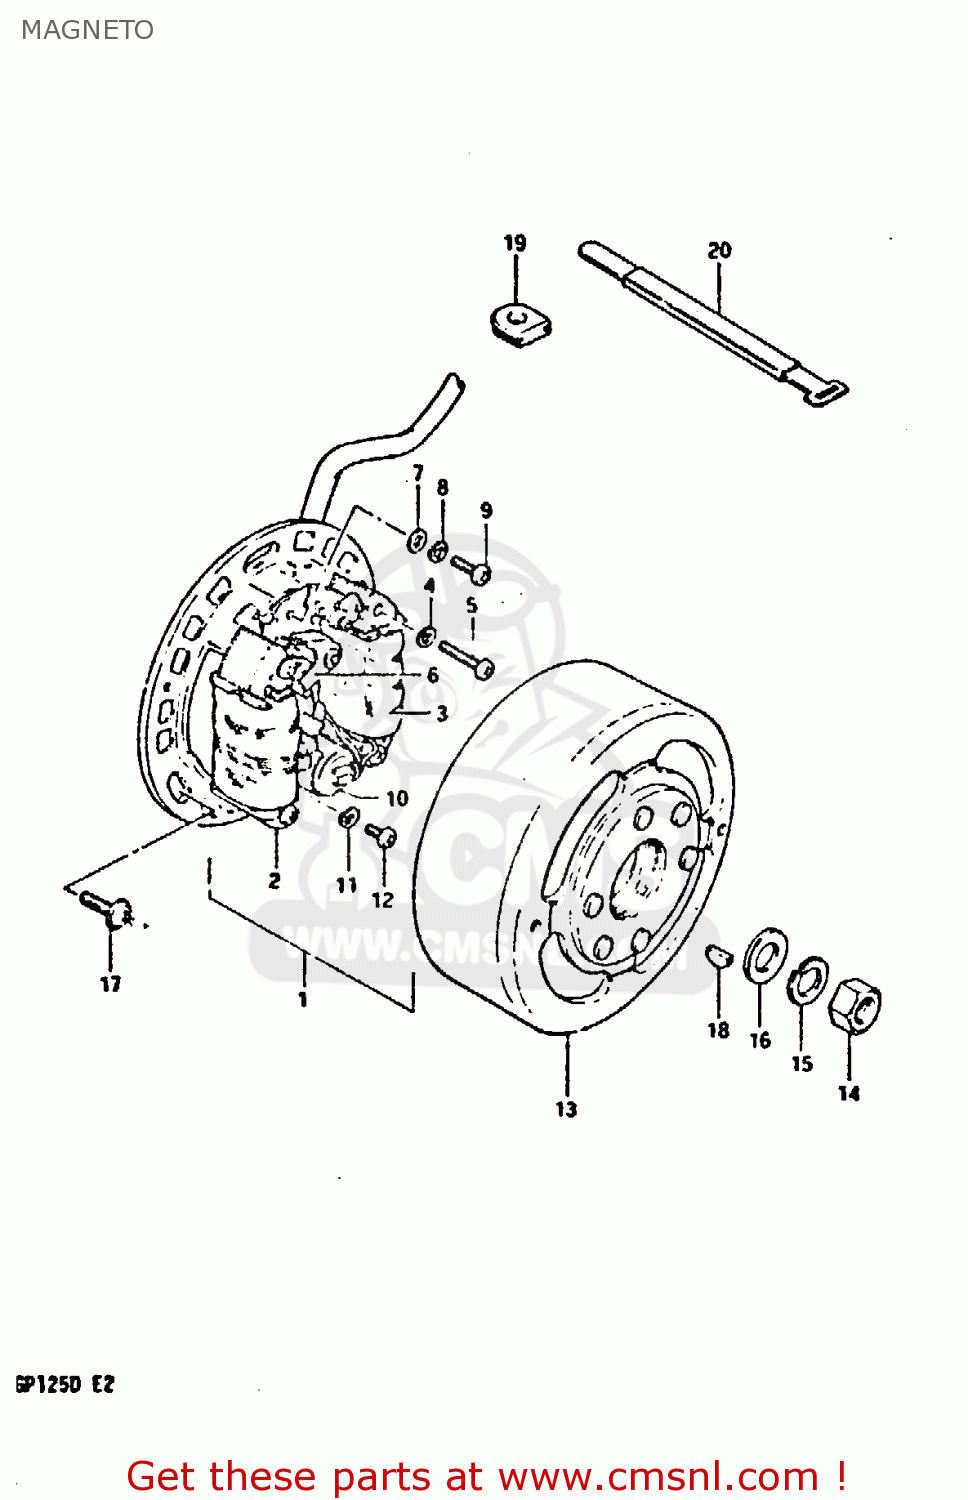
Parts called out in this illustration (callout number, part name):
1	STATOR ASSY
2	COIL, LIGHTING
3	COIL,PRIMARY
4	LOCK WASHER
5	SCREW (4X30)
6	POINT ASSY,CONTACT
7	WASHER
8	LOCK WASHER
9	SCREW(4X10)
10	CONDENSER
11	LOCK WASHER
12	SCREW
13	ROTOR ASSY
14	NUT (10MM)
15	LOCK WASHER
16	WASHER
17	SCREW(5X14)
18	KEY
19	GROMMET
20	CLAMP
